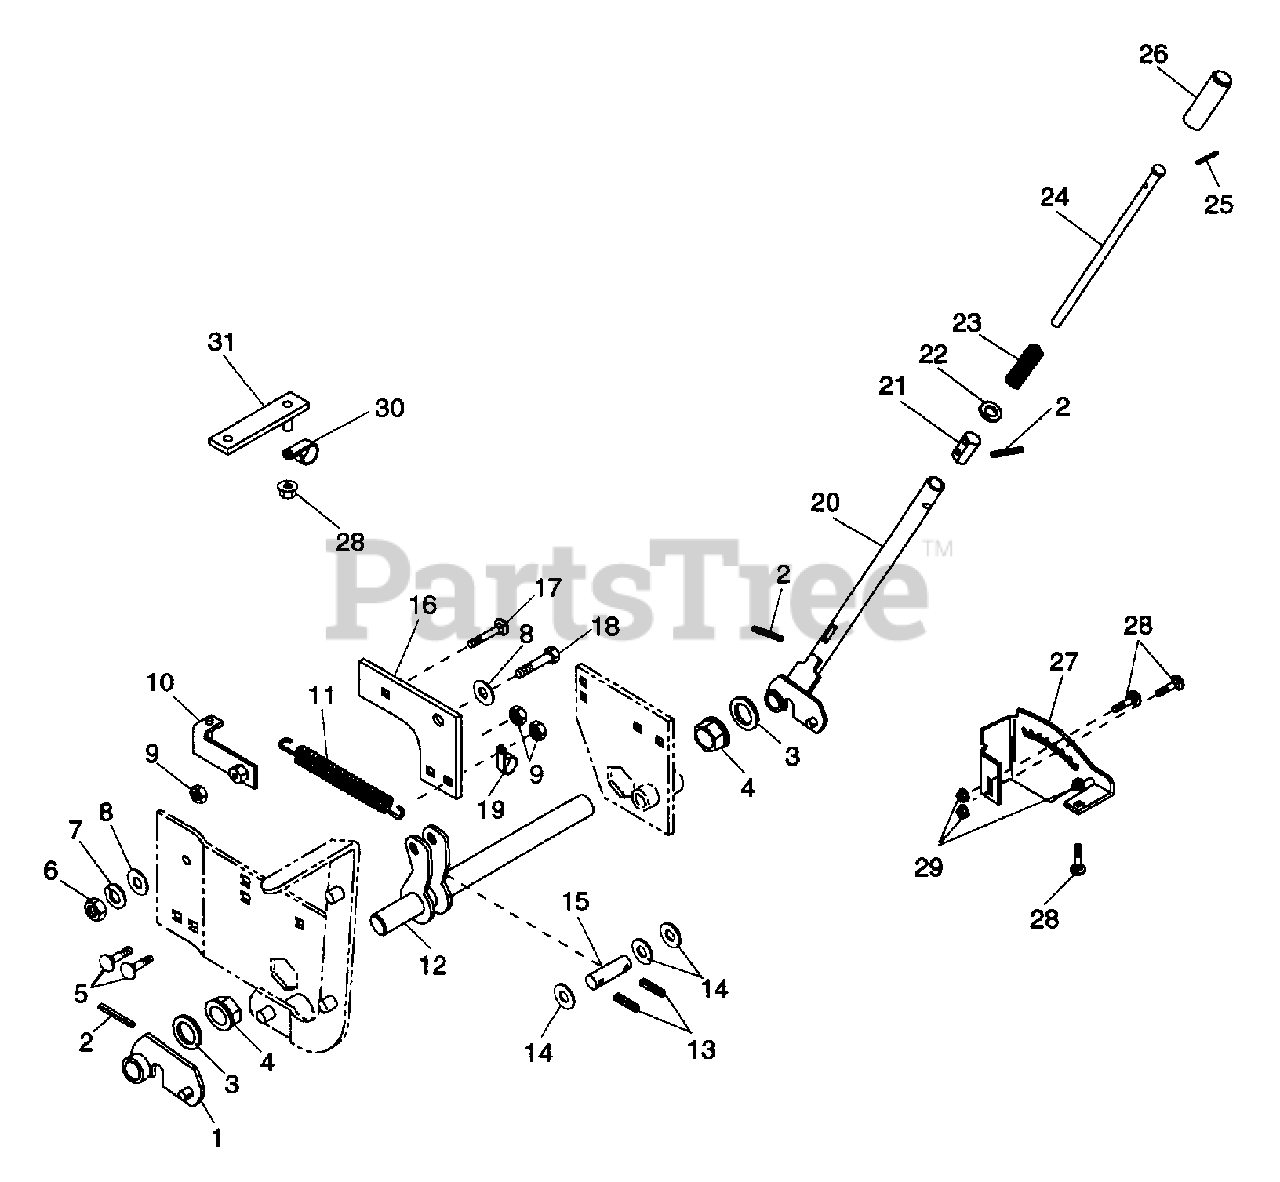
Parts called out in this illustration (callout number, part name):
1	LIFT ARM RH
2	PIN-GRV .250X1.50 TP A
3	WSHR-FL-STL 1.015X1.500X.125
4	BSHG-FLG 1.000X1.25X.49X1.56HX
5	BLT-RDHDSQSHNK .38-16X1.00 PL
6	NUT .50-13 PL
7	WSHR-LK .500X.151 HVY PL
8	WSHR-FL-STL .511X1.441X.125 PL
9	NUT-LK-CTR .375-16 GR A PL
11	SG-TENS .188X1.50X8.5 WLD 57
12	LIFT PIVOT
13	PIN-ROLL .188X1.00
14	WSHR-FL-STL .520X.827X.062 YZ
17	BLT-RDHDSQNK .38-16X1.75 PL
18	BLT-HEX .50-13X1.25 PL GR2
19	J-CLAMP
20	LIFT LEVER
22	WSHR-FL-STL .458X.750X.06 PL
23	SG-COMP .048X.59X2.06 WLD9
25	PIN-DWL .188X1.25
26	HANDLE GRIP
27	LIFT QUAD
28	BLT-RDHDSQNK .31-18X1.00 PL
29	NUT-FLG. .312-18 PL
30	J-CLAMP
31	BRACKET
